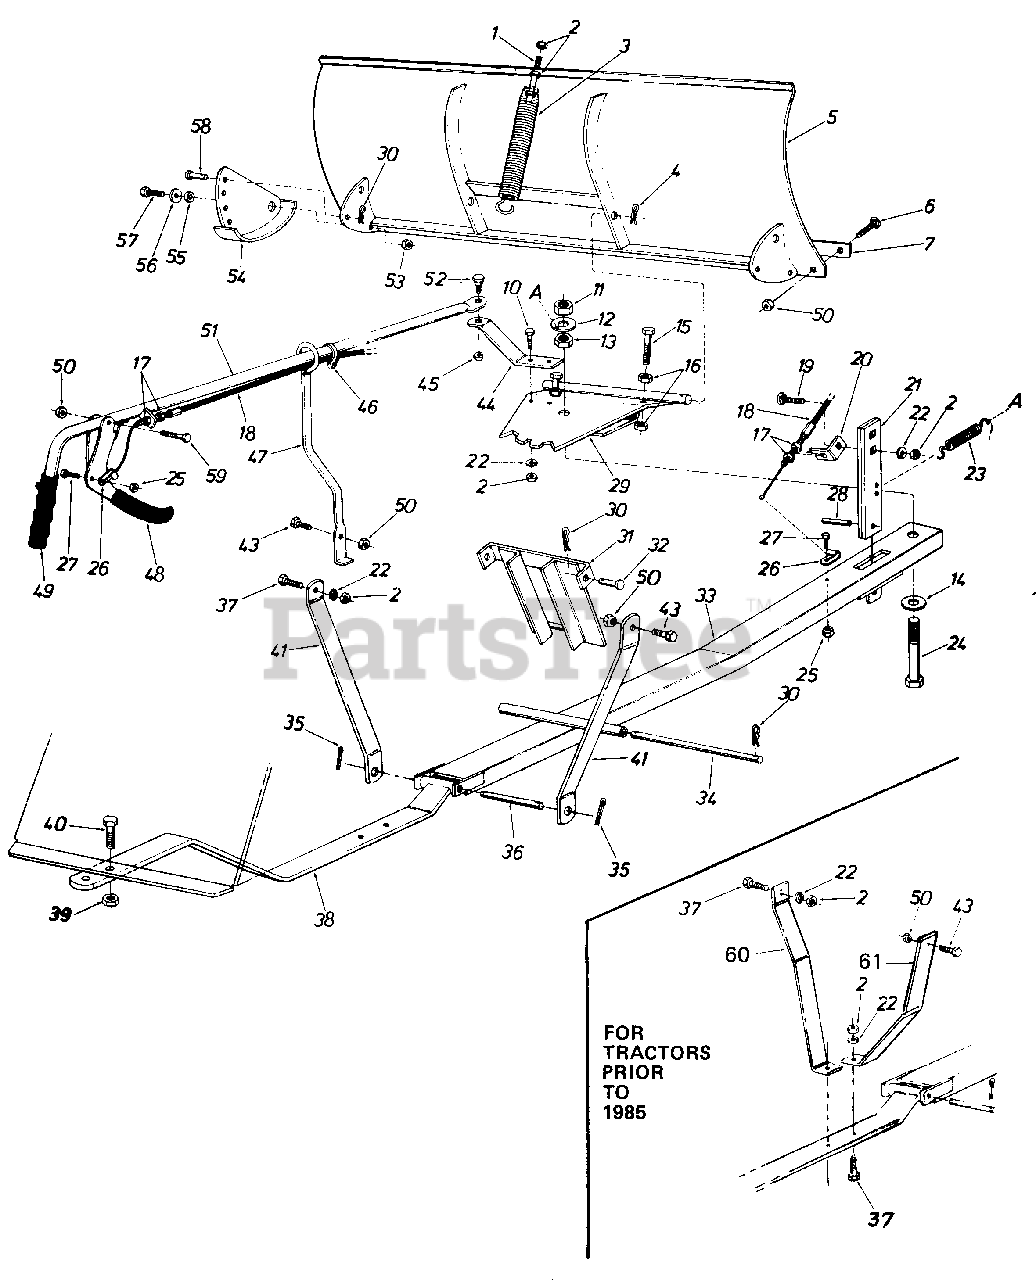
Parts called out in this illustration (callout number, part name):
1	Hex Scr. 3/8-16 x 4.50" Lg.*
2	Hex Nut 3/8-16 Thd.
3	Blade Adjustment Spring
4	Hair Pin Cotter 5/32" Dia.
5	48" Blade Ass'y.
6	Carriage Bolt 5/16-18 x.75" Lg.*
7	Wear Plate 48"
10	Hex Scr. 3/8-16 x 1.00" Lg.*
11	Hex L.-Nut 3/4-10 Thd.
12	Fl.-Wash. .810" I.D. x 2.00" O.D.
13	Hex Jam Nut 3/4-10 0 Thd.*
14	Fl.-Wash..810" I.D. x 2.00" O.D.
15	Hex Scr. 1/2-13 x 2.00" Lg.*
16	Hex Nut 1/2-13 Thd.*
17	Hex Jam Nut 5/16-24 Thd.*
18	Control Cable Ass'y.
19	Carriage Bolt 3/8-16 0 x 1.25" Lg.*
20	Cable Guide Bracket
21	Angle-Lock Bar
22	L.-Wash. 3/8" Scr.*
23	Angle Lock Spring
24	Hex Scr. 3/4-10 x 4.00" Lg.
25	Hex L.-Nut 1 /4-20 Thd.
26	Clevis Lanyard Fitting
27	Hex Scr. 1/4-20 x .75" Lg.*
28	Spring Pin Spirol 1/4" Dia. x 1.00"-Lg.
29	Pivot Plate Ass'y.
30	Hair Pin Cotter 3/32" Dia.
31	Guide Bracket Ass'y.
32	Clevis Pin 1/2" Dia. x 1.00" Lg.
33	Push Bar Ass'y.
35	Cotter Pin 5/32" Dia. x 1.00" Lg.*
37	Hex Scr. 3/8-16 x 1.25" Lg.*
38	Hanger Bracket Ass'y.
39	Hex L.-Nut 5/8-11 Thd.
40	Hex Scr. 5/8-11 x 1.50" Lg.*
41	Hanger Link
43	Hex 5/16-18 x 1.00" Lg.*
44	Blade Pivot Bracket
45	Hex L.-Nut 3/8-16 Thd.
46	Nylon Cable Tie
47	Tube Guide Ass'y.
48	Clutch Grip Ass'y.
49	Grip-3/4" Handle
50	Hex L-Nut 5/16-18 Thd.
51	Tube Handle Ass'y.
52	Shld. Scr.-Special 3/8-16 Thd.
53	Hex L.-Nut 3/8-16 0 Thd.
54	Skid Assembly
55	Spacer
56	Fl.-Wash. .385" I.D. x 1.00" O.D.
57	Hex Scr. 3/8-16 x .75" Lg.*
58	ClevisPin5/16" Dia. x . 75" Lg.*
59	Hex Scr. 5/16-18 x 1.50" Lg.
60	Mounting Brkt.-L.H.
61	Mounting Brkt.-R.H.
